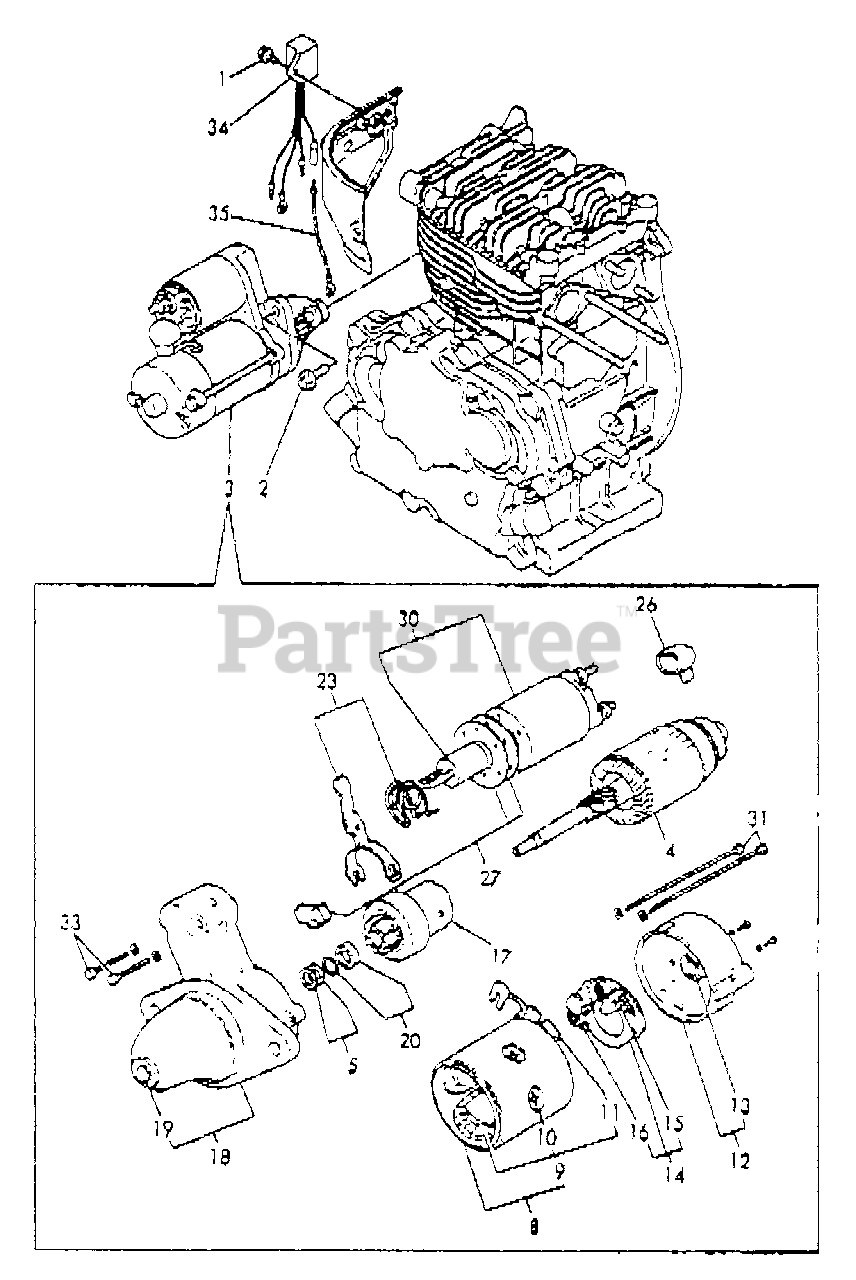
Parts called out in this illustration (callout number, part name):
1	BOLT - 6X12 -- PLATED
2	BOLT - 8X20 -- PLATED
3	STARTING MOTOR
4	ARMATURE ASSY
5	THRUST WASHER KIT
8	YOKE ASSY
9	IGNITION COIL ASSY
10	SCREW, POLE CORE
11	BRUSH - ( + )
12	COVER ASSY - REAR
13	METAL
14	BRUSH HOLDER ASSY
15	BRUSH - ( - )
16	SPRING, CHOKE
17	PINION ASSY
18	GEAR CASE ASSY
19	METAL
20	STOPPER SET, PINION
23	SHIFT LEVER SET
26	CAP, TERMINAL
27	COVER SET, DUST
30	MAGNET SWITCH ASSY
31	BOLT
33	BOLT - 6X32
34	RECTIFIER
35	WIRE
